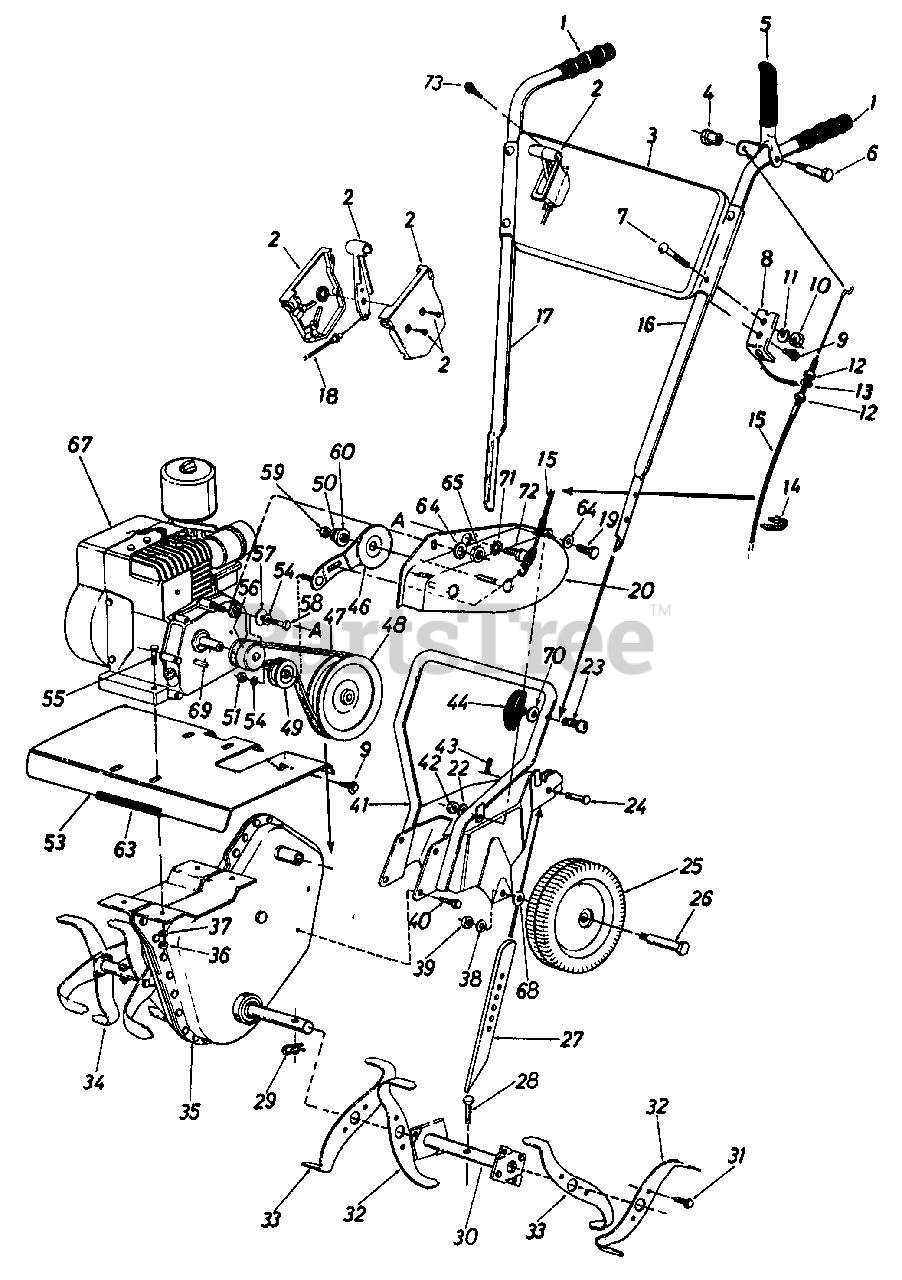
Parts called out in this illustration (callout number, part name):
2	Throttle Control Box Ass'y.
3	Handle Panel
4	Shoulder Nut
5	Clutch Grip Ass'y.
6	Shoulder Bolt 3/8 x 1.160" Lg.
7	Carriage Bolt 5/16-18 x 1.5" Lg.*
8	Cable Support Bracket
9	Hex Wash. Hd. Self-Tap Scr. 1/4-20 x .50" Lg.
10	Hex Nut 5/16-18 Thd.
11	L-Wash 5/16" I.D.
12	Hex Jam Nut 5/16-24 Thd.
13	L-Wash. 5/16" I.D.
15	Clutch Control Cable
19	Hex Bolt 1/4-20 x .75" Lg.
20	Belt Cover Ass'y.
22	L-Wash. 1/4" I.D.
23	Curved Hd. Bolt 5/16-18 x 1.75" Lg.
25	Wheel Ass'y. Comp. 7.0" x 1 .5
26	Shoulder Bolt
29	Hairpin Cotter
36	Hex Nut 5/16-18 Thd.
37	L-Wash. 5/16" I.D.*
38	L-Wash. 3/8" I.D. (Heavy Duty)
39	Hex Cent. L-Nut 3/8-16 Thd.
40	Hex Wash. Hd. Self-Tap Scr. 5/16-18 x .50" Lg.
43	Internal Cotter Pin
44	Hand Knob
46	Idler Arm Ass'y.
47	Belt 3/8" x 29" Lg.
48	Chain Case Pulley 5-1/2 x 1/2"
50	L-Wash. 5/16" I.D.
51	Hex Nut 3/8-24 Thd.
53	Tine Shield
54	L-Wash. 3/8" I.D.
55	Hex Bolt 5/16-18 x 1.50" Lg.
56	Engine Pulley 3/8 V x .75 I.D. x 2" O.D.
57	Fl-Wash. .385" I.D. x 1.00" O.D.
58	Hex Bolt 3/8-24 x 1.00" Lg.
59	Hex Nut 5/16-18 Thd.
60	Shld. Spacer .50" Dia. x .133
63	Trim Strip-4"
64	Fl-Wash. .281" I.D. x .500" O.D.
65	Hex Cent. L-Nut 1/4-20 Thd.
67	Engine
68	Bell-Wash.
69	Square Key 3/16 x 3/4" Lg.
71	Ext. L-Wash. 1/2" I.D.
72	Hex Bolt 1/2-20 x .75" Lg.
73	Self-Tap Scr. #10 x .5" Lg.
